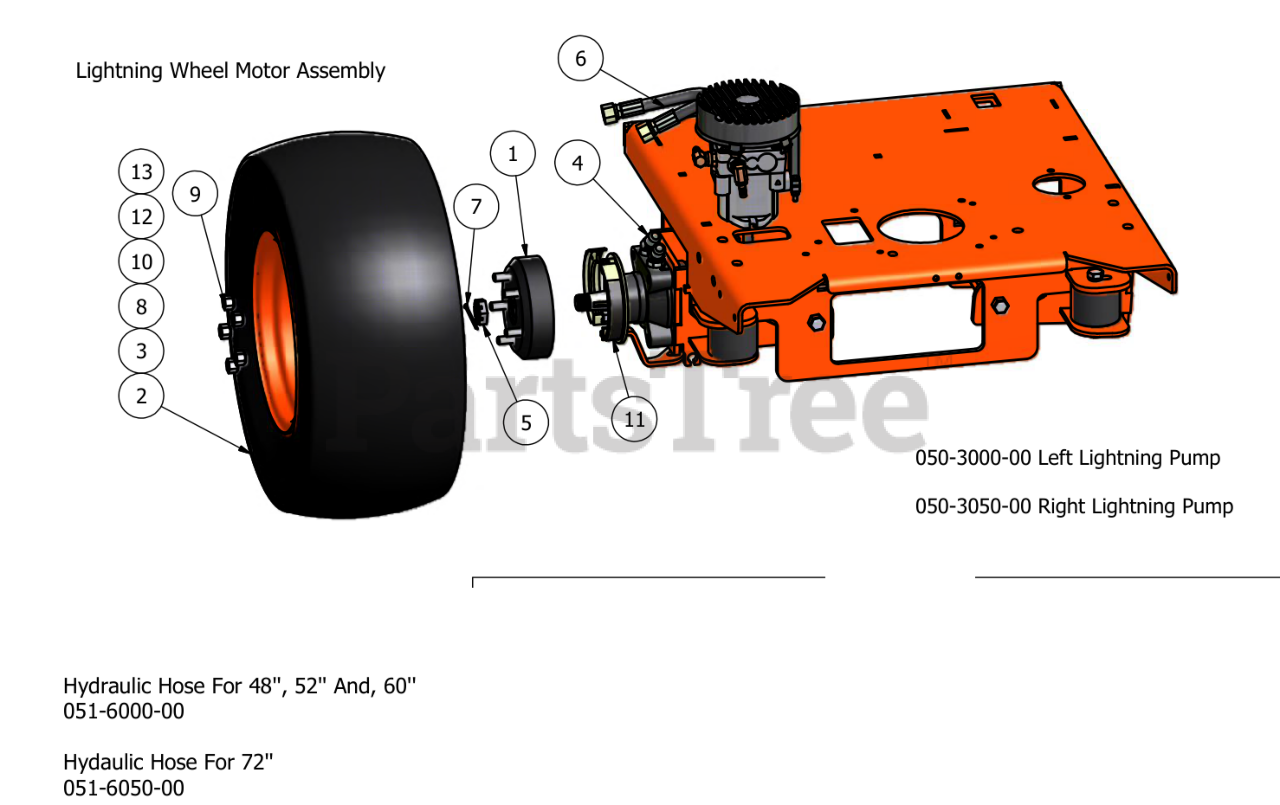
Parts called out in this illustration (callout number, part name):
1	Brake Drum
2	24" Tire and Wheel Assembly
3	12" Rim - 60"&72" Cut
4	Hydraulic Fitting (Wheel Motor)
5	Castle Nut
7	1/8"x2 1/4" Cotter Pin
8	24x12-12 Tire 60"&72" Cut
10	23x10.50-12 Tire & Wheel
11	Brake Pads
12	23x10.50-12 Tire
13	12" Rim 48" & 52" Cut
